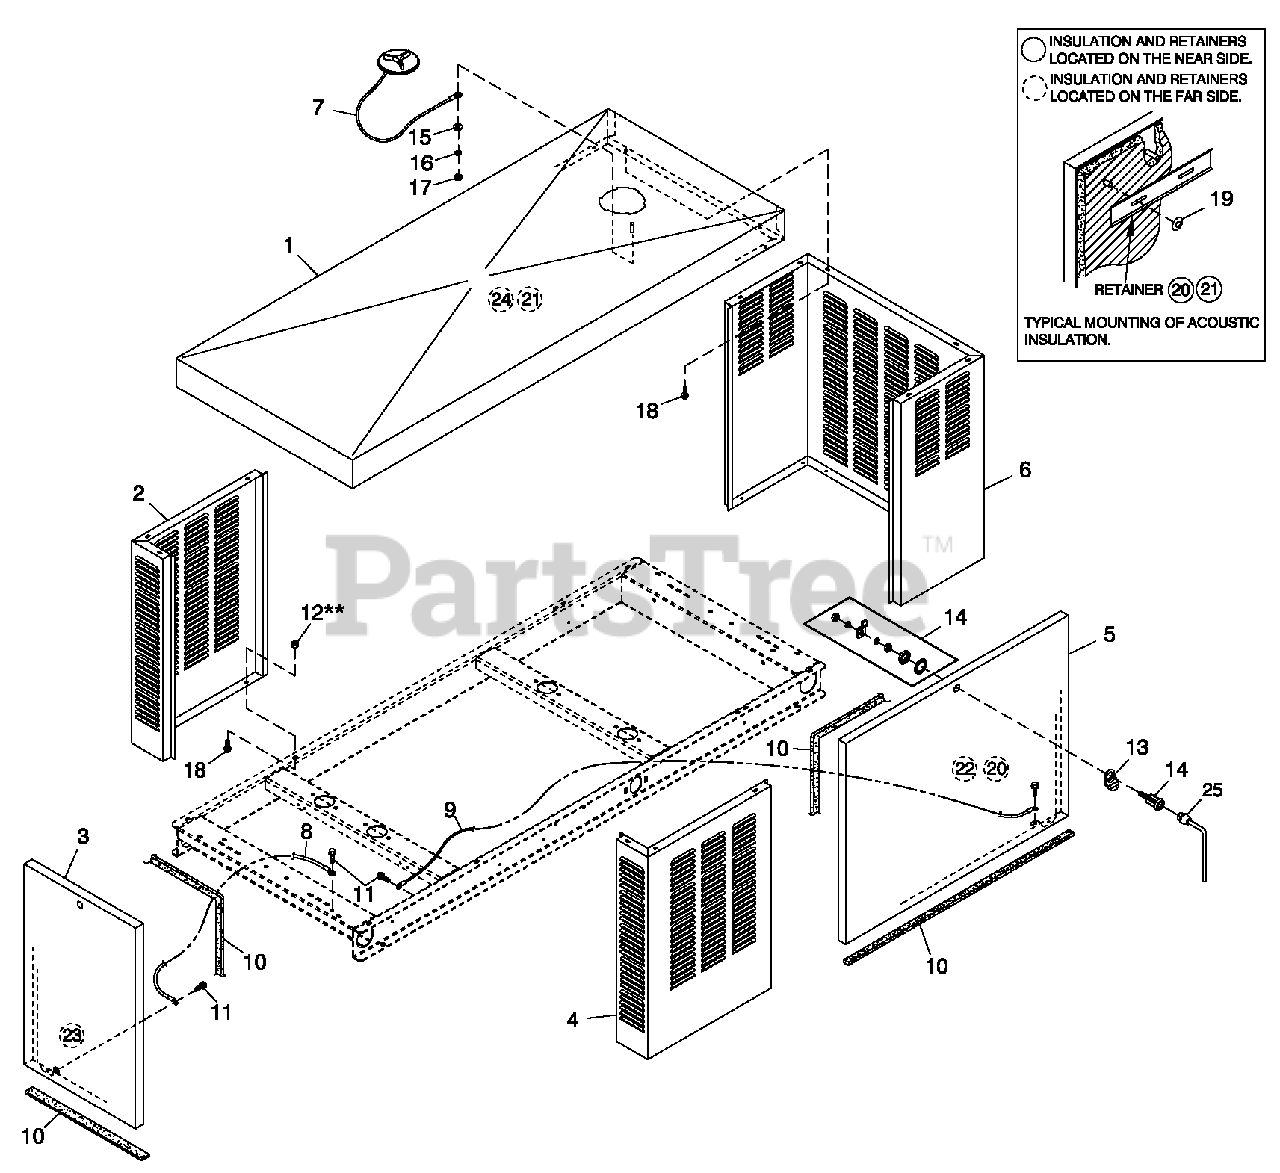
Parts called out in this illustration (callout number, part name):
1	ROOF C1 CPL
2	CORNER POST LH SIDE C1 CPL
3	DOOR REAR C1 CPL
4	CORNER POST RH SIDE C1 CPL
5	DOOR LH & RH SIDE C1 CPL
6	DUCT FRONT DISCHARGE C1 CPL
7	ASSEMBLY COVER ACCESS
8	ASSY WIRE 14AWG 13.8" GRN/YEL
9	ASSY WIRE 14AWG 33.5" GRN/YEL
10	GASKET EXTRUDED TRIM (356" LG)
11	SCREW HWHTF M6-1.0 X 16
12	NUT HEX LOCK M6-1.0 SS NY INS
13	TAB PULL
14	VISE-ACTION LATCH SLOTTED CIR
15	WASHER FLAT 1/4-M6 ZINC
16	WASHER LOCK M6-1/4
17	NUT HEX 1/4-20 STEEL
18	SCREW THF M6-1 X 16 N WA Z/JS
19	WASHER SELF LOCKING DOME
20	RETAINER INSULATION (820)
21	RETAINER INSULATION (450)
22	INSULATION SIDE DOOR C1
23	INSULATION REAR DOOR C1 CPL
24	INSULATION ROOF C1 CPL
25	KEY VISE-ACTION LATCH SLOT CIR
